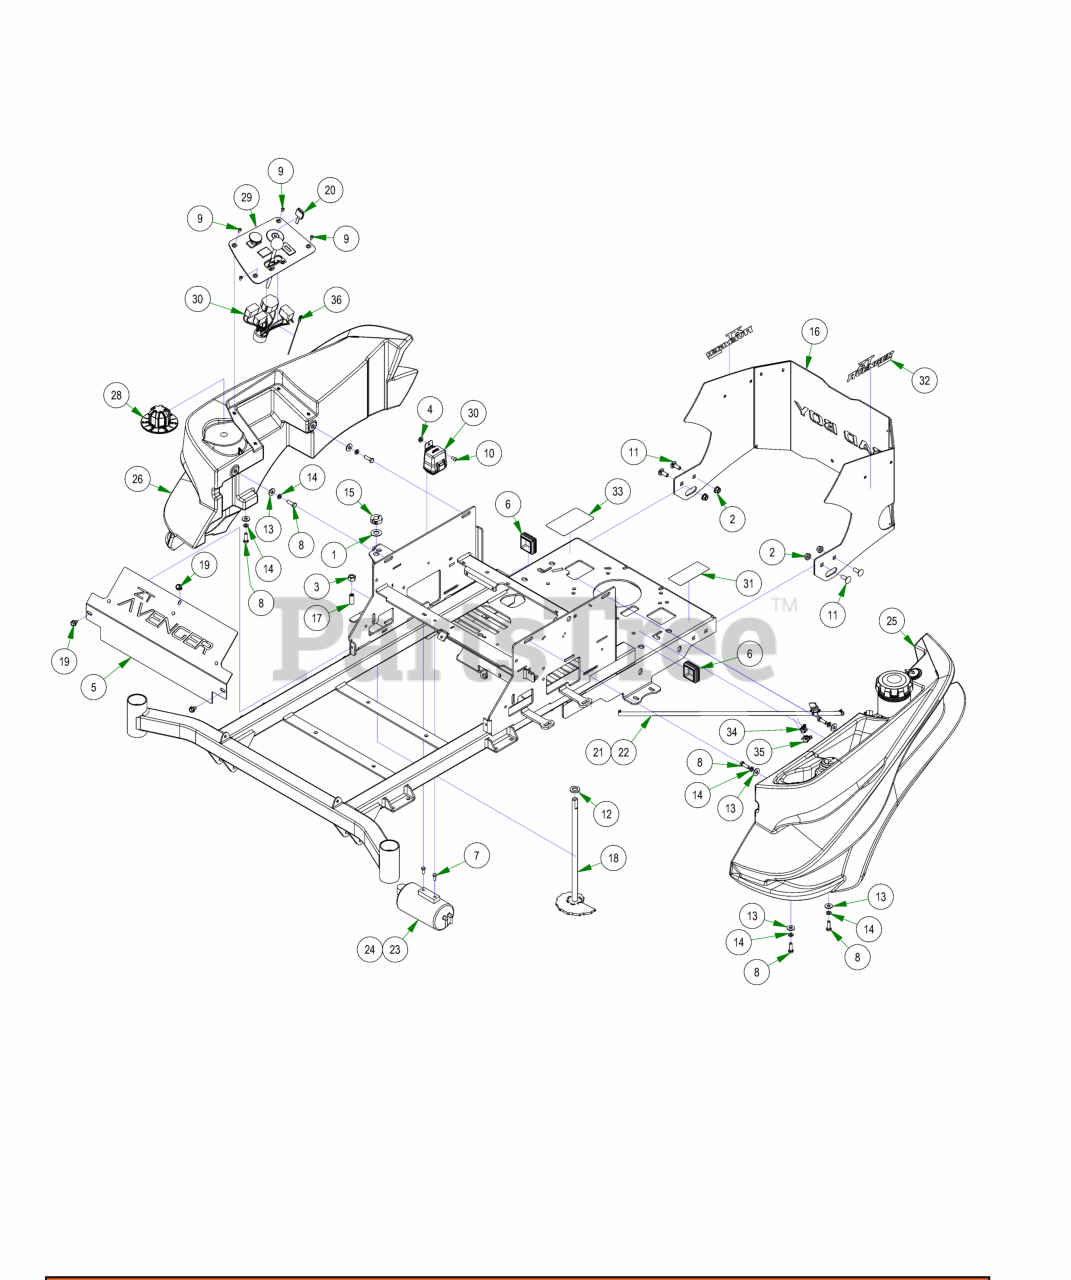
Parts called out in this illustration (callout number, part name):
1	.625 ID x 1.250 OD x .062 THK F/W Nylon
2	3/8-16 NYLON INSERT FLANGE LOCKNUT (GR.F) ZINC
3	1/2-13 HEX NUT ZINC
4	1/4-20 HEX SERRATED FLANGE NUT HARD/ZINC
5	2023 ZT Avenger Cooler Cover Assembly
6	2X2 Frame Plug
7	M6-1.0 X 16MM DIN 933 HEX TAP BOLT (CL 8.8) ZINC
8	5/16-18 X 1 HEX CAP SCREW (GR.5) ZINC
9	10-32 X 3/8 BUTTON SOCKET CAP SCREW 18-8 STAINLESS
10	1/4-20 X 1/2 BUTTON SOCKET CAP SCREW 18-8 STAINLESS
11	3/8-16 X 1 CARRIAGE BOLT (GR.5) ZINC
12	.635 ID X 1.120 OD X .140 THICK FLAT WASHER NYLON
13	5/16 USS FLAT WASHER (7/8 OD) ZINC
14	5/16 SPLIT LOCKWASHER ZINC
15	5/8" Split Collar
16	2022 ZT Avenger Rear Cover Assembly
17	Dial Rod Plunger
18	ZT Deck Height Bar Assembly
19	5/16-18 X 1/2 HWH unslot (F) tcs zinc
20	Ignition Key
21	15" Fuel Line Assembly
22	37" Fuel Line Assembly
23	ZT/Mav EPA Cannister Assy
24	Avenger Kohler EPA Cannister Assy
25	Left Fuel Tank
26	Right Side Console
27	2024 MZ-Avenger 54-60 Frame
28	MZ/ZT Deck Height Dial
29	2023 Control Panel Assembly
30	2024 Wiring Harness with Clips
31	2024 EPA Build Date Punch Decal
32	Avenger Back Plate Decal
33	Pump Belt Route Decal-Pump Plate
34	Edge Clip With Ziptie
35	Edge Clip With Ziptie
36	2017 MZ/ZT/MAV Tach Wire Assy
